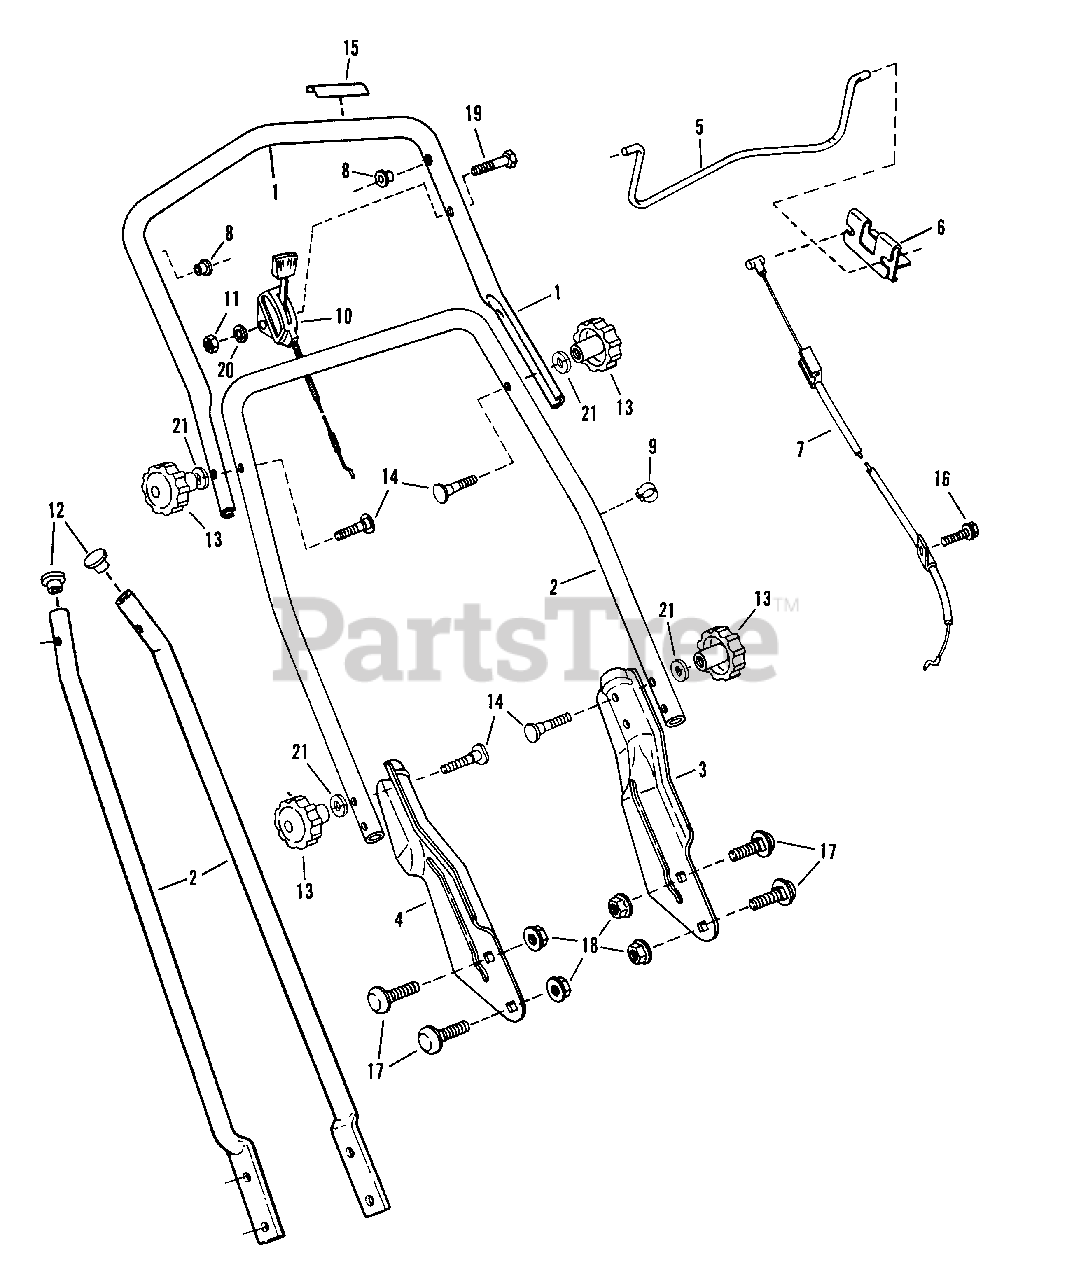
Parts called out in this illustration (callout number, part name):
1	HANDLE, Upper
2	HANDLE, Middle
3	HANDLE, Lower Left Hand
4	HANDLE, Lower Right Hand
5	CONTROL, Blade
6	CLIP, Blade Control
7	CABLE, Blade Control (Tecumseh 4-Cycle)
8	BUSHING
9	CLIP, Wiring Harness
10	CONTROL, Throttle (Tecumseh)
11	NUT, 1/4-28 Hex
12	PLUG
13	KNOB, 5/16-18
14	SCREW, 5/16-18 x 2" Curved Head
15	DECAL, Blade Control
16	SCREW, #10-32 x 5/16" Sems
17	BOLT, 5/16-18 x 5/8" Short Neck Carriage
18	NUT, 5/16-18 Hex Flange Lock
19	SCREW, 1/4-28 x 1-3/4" Hex Head Cap
20	WASHER, 1/4 Internal Tooth Lock
21	WASHER, 5/16 Internal Tooth Lock
